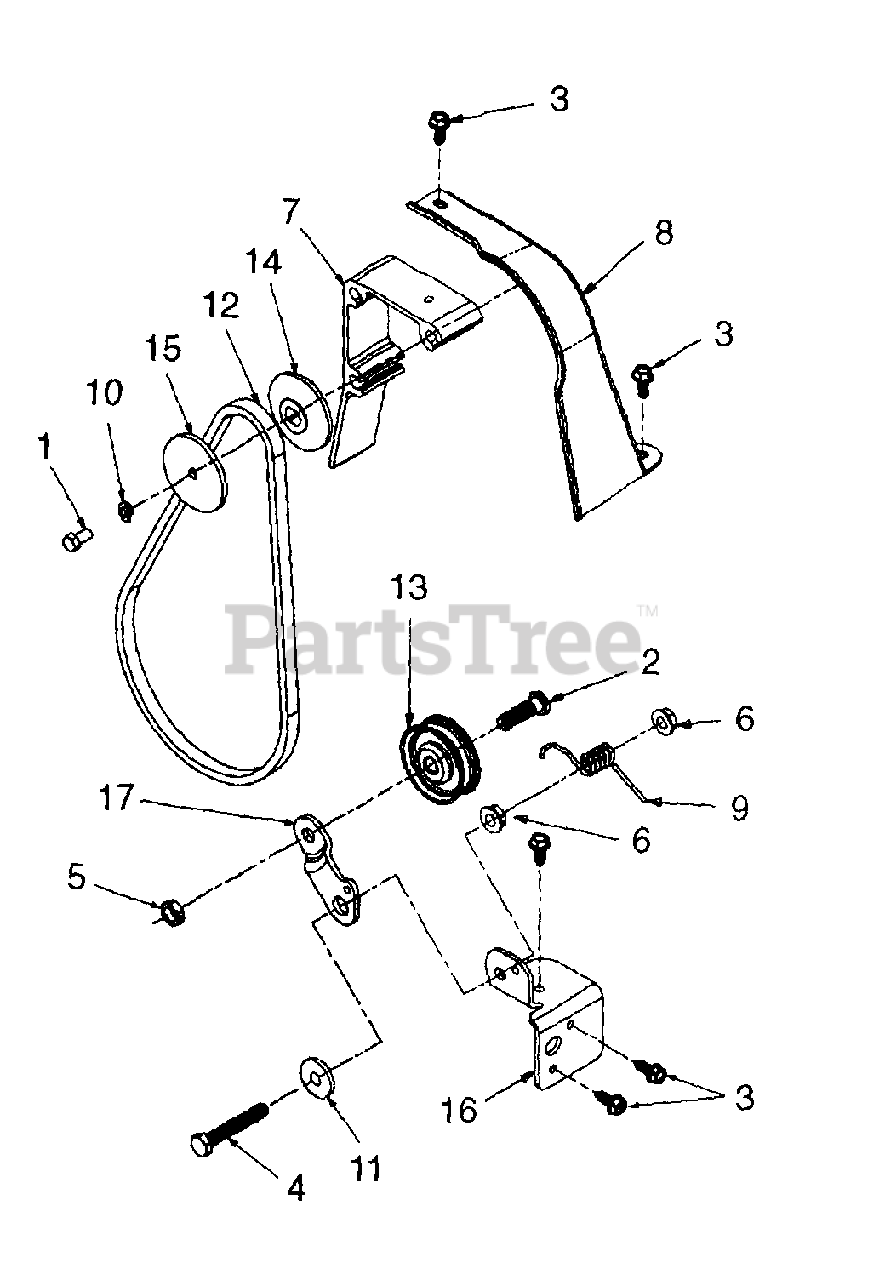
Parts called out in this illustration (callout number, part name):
1	Screw, Hex Cap, 1/4-28 x .50
2	Screw, Hex Cap, 3/8-16 x 1.25
3	Screw, Hex Wash Hd Tapp. 1/4-14 x .625
4	Screw, Hex Cap, 5/16-18 x 2.0
5	Nut, Hex Cent-L Jam, 3/8-16
6	Nut, Hex Flange Lock, 5/16-18
7	Adapter, Engine Mtg
10	Washer, Lock, 1/4
11	Shoulder Spacer, .50 ID x .27 Lg
12	V-Belt, 3/8 x 29.0 Lg
13	Pulley, Flat Idler
14	Pulley Half, 2.0 Dia
15	Pulley Half, 2.0 Dia
16	Bracket, Idler Pivot
17	Bracket, Idler
